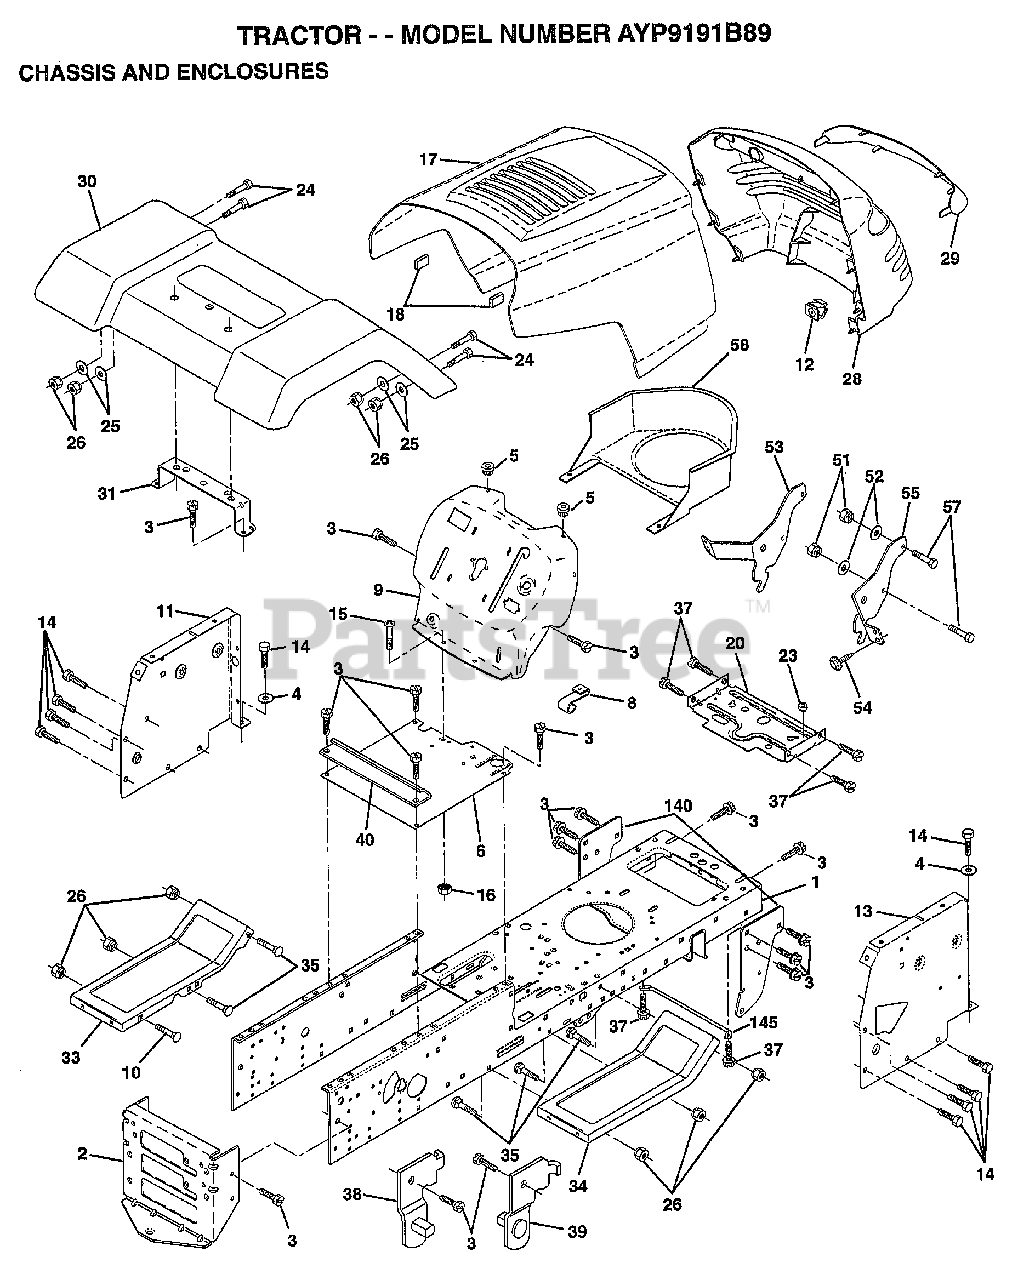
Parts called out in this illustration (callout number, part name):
3	SCREW
4	WASHER
5	BUMPER-HOOD/DASH
6	SADDLE
8	"CLIP,INSULATOR"
9	DASH SILKSCREEN
11	"PANEL-DASH,LH"
12	CLIP.TINNERMAN
14	SCREW LT
15	SCREW
17	HOOD.STEEL.ASSY
20	"PLATE-MTG,BATT/FU"
24	BOLT
25	WASHER
26	NUT
28	GRILLE-MS428
29	LENS GRILLE
30	FENDER.PNT.ASSY
31	BRACKET SUPT FEND
33	FOOTREST.LH.LT/GT
34	FOOTREST.RH.LT/GT
35	BOLT
38	BRACKET ASM LH
39	BRACKET ASM RH
40	SPACER FENDER LT
51	NUT
52	WASHER
53	BRACKET.GRILLE.LH
54	SCREW.HEX.WS.HD
55	BRACKET.GRILLE.RH
58	DUCT.AIR.B&S.18HP
140	BRKT SUSPENSION
145	"ROD POVOT,CHASSIS"
